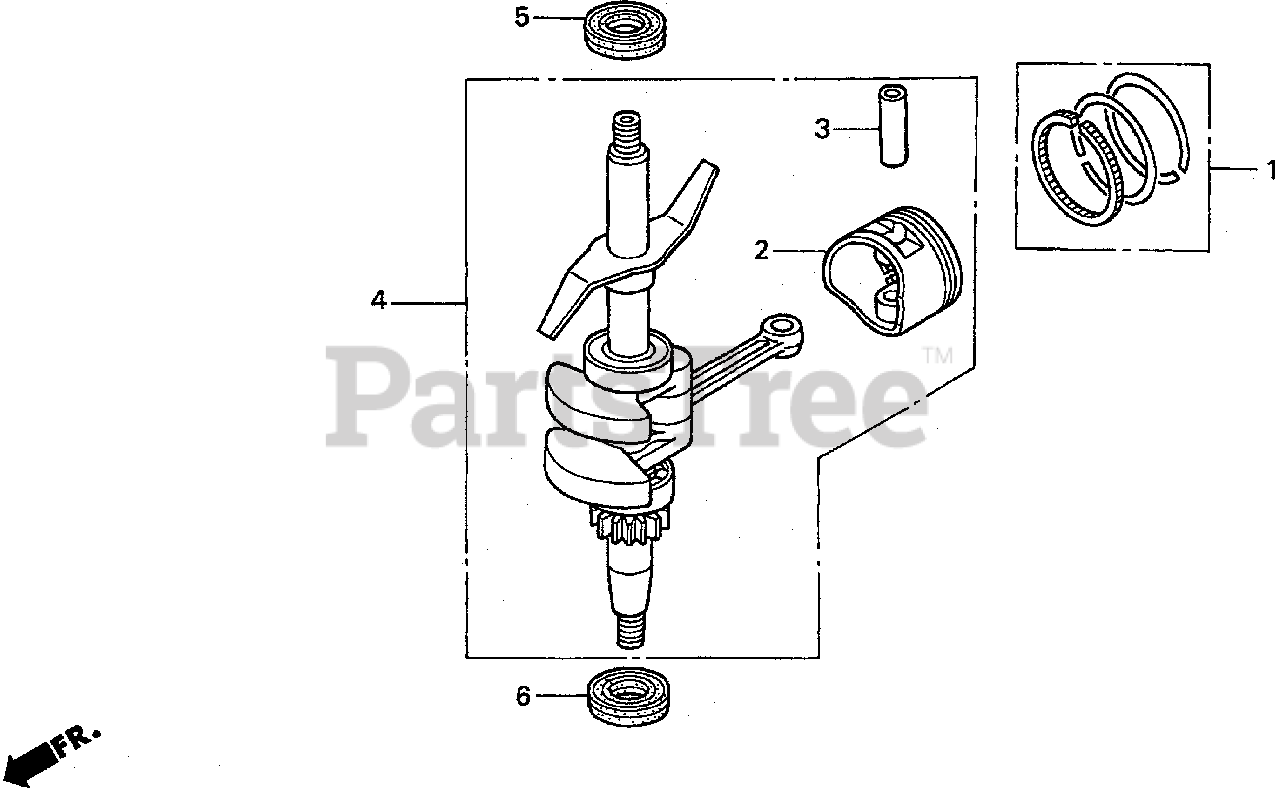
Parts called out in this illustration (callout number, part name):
1	RING SET, PISTON
2	PISTON
3	PIN, PISTON
4	CRANKSHAFT COMP.
5	OIL SEAL (12X25X6)
6	OIL SEAL (15X25X6)
